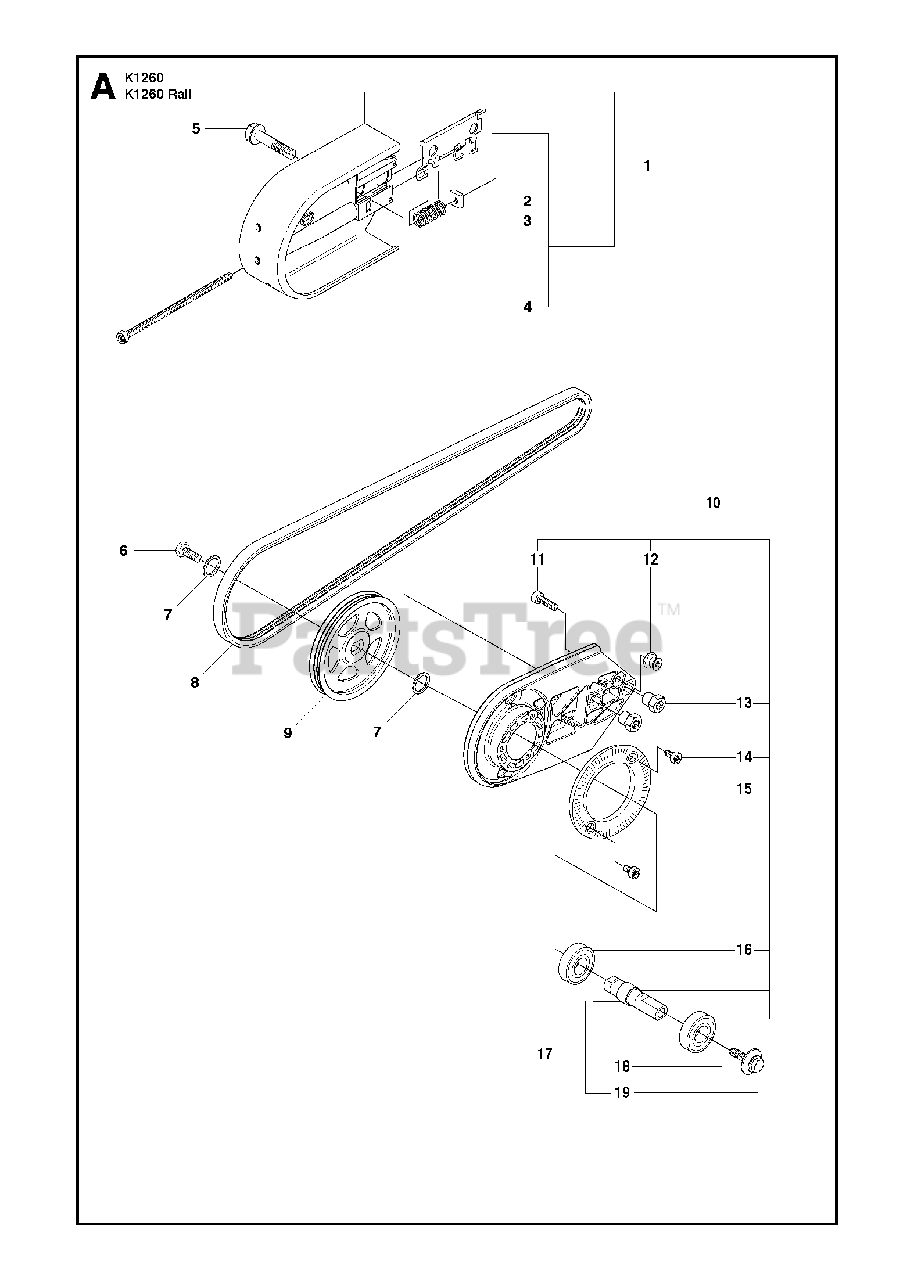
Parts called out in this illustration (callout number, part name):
1	BELT GUARDIncl. 2 - 4
1	BELT GUARD"Rail 14"", Incl. 2 - 4"
1	BELT GUARD"Rail 16"", Incl. 2 - 4"
3	COMPRESSION SPRING
4	SCREW CITXSCM
8	BELT"14"", 16"", Rail 14"""
8	BELT"Rail 16"""
10	BEARING HOUSINGIncl. 11 - 15
11	SCREW ITXSCM
12	TORSION STOP
14	SCREW ITXSCM
16	BALL BEARING
17	SHAFTIncl. 18 - 19
